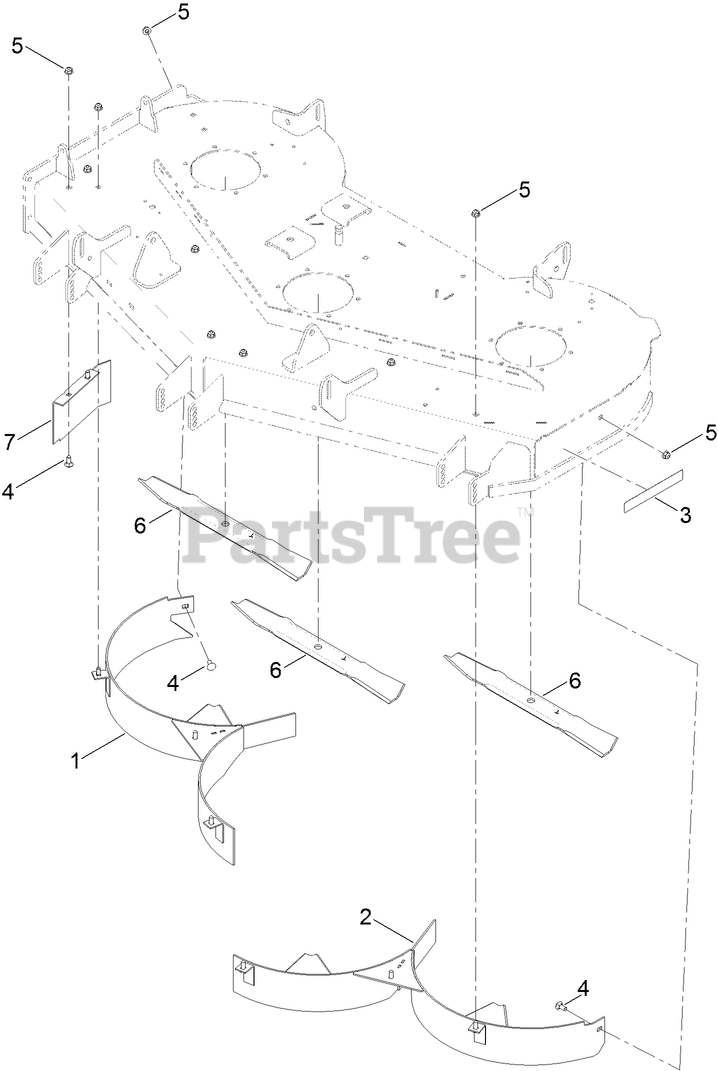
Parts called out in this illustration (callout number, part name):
1	BAFFLE-RECYCLER
2	BAFFLE-RECYCLER, LH
3	DECAL-RECYCLER
4	BOLT-CARR
5	NUT-HF, NI
6	BLADE-MULCH, 18.75 INCH
7	GUARD-BAFFLE
